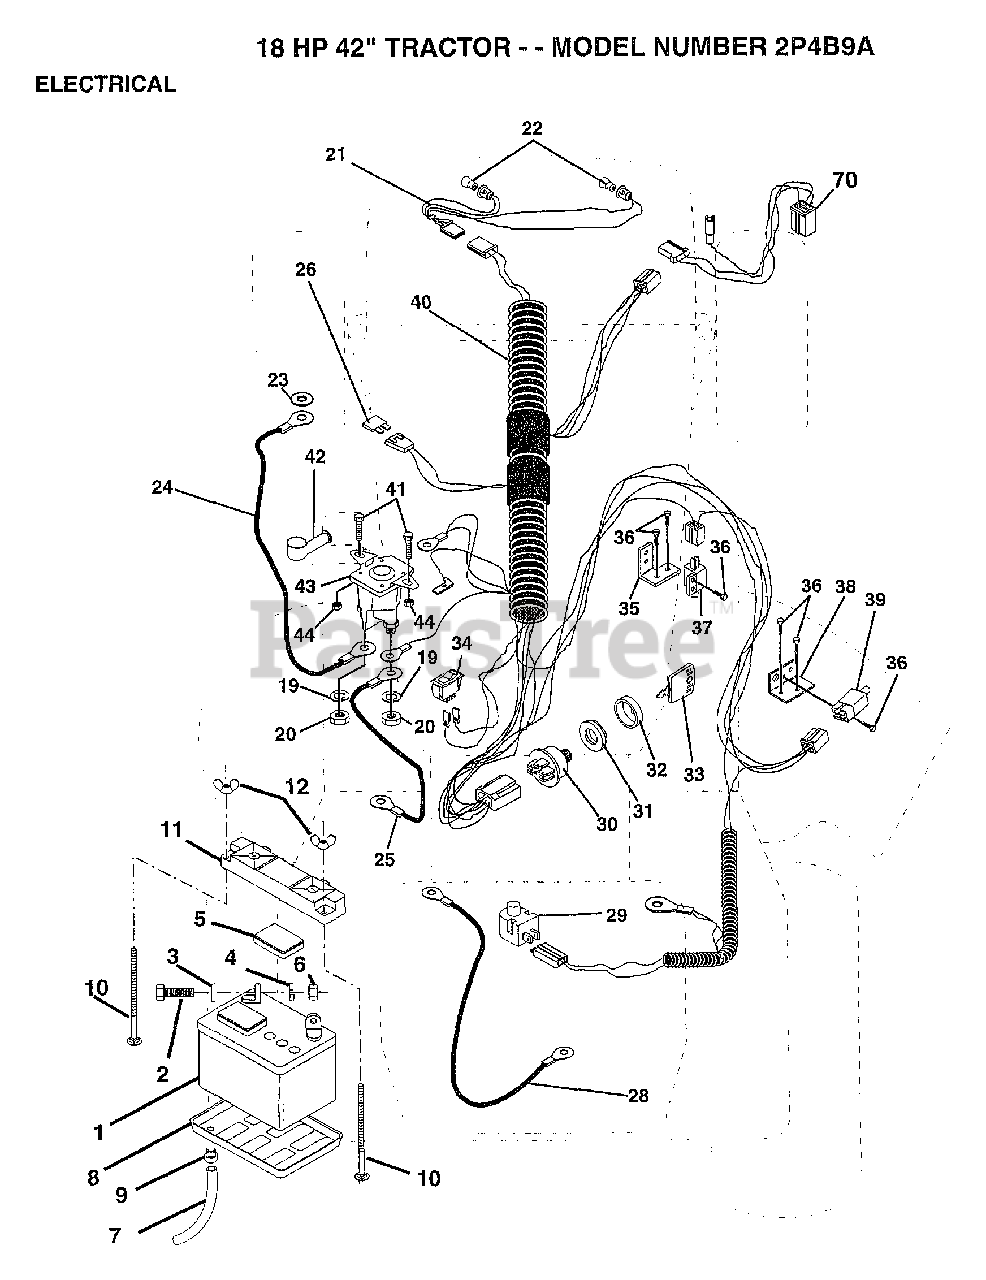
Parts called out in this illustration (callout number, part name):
2	BOLT LT
3	WASHER
4	LOCKWASHER
5	"CAP,BATTERY "
7	"DRAIN TU T, BATT"
8	"TRAY T, BATTERY"
9	HOSE CLAMP T
10	BOLT
20	NUT
21	"HARNESS,LIGHT SOC"
22	HEADLAMP BULB
23	LOCKWASHER
24	CABLE ASM.
25	CABLE-BATTERY T
26	FUSE HYT
28	CABLE T
29	SWITCH SEAT
32	COVER KEY SWITCH
33	KEY MLD GEN DELTA
34	SWITCH LT
35	BRACKET LT
36	SCREW
37	SWITCH-INTER. GT
38	BRACKET SWITCH IN
39	SWITCH INTERLOCKT
40	HARNESS IGN DASH
41	BOLT HXHD FIN
44	NUT HXKEP 1/4X20
70	HARNESS ENG DUAL
